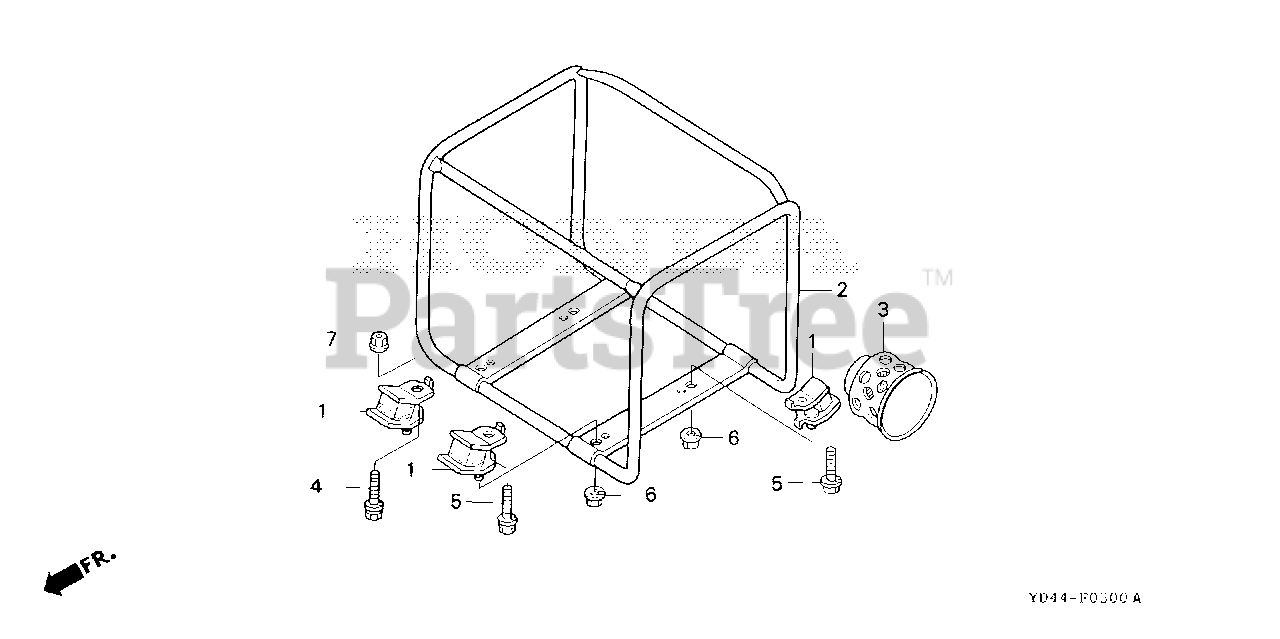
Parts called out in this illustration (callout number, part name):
1	RUBBER (LOWER)
3	STRAINER
4	BOLT-WASHER (10X40)
5	BOLT-WASHER (10X25)
6	NUT-WASHER (8MM)
7	NUT-WASHER (10MM)
